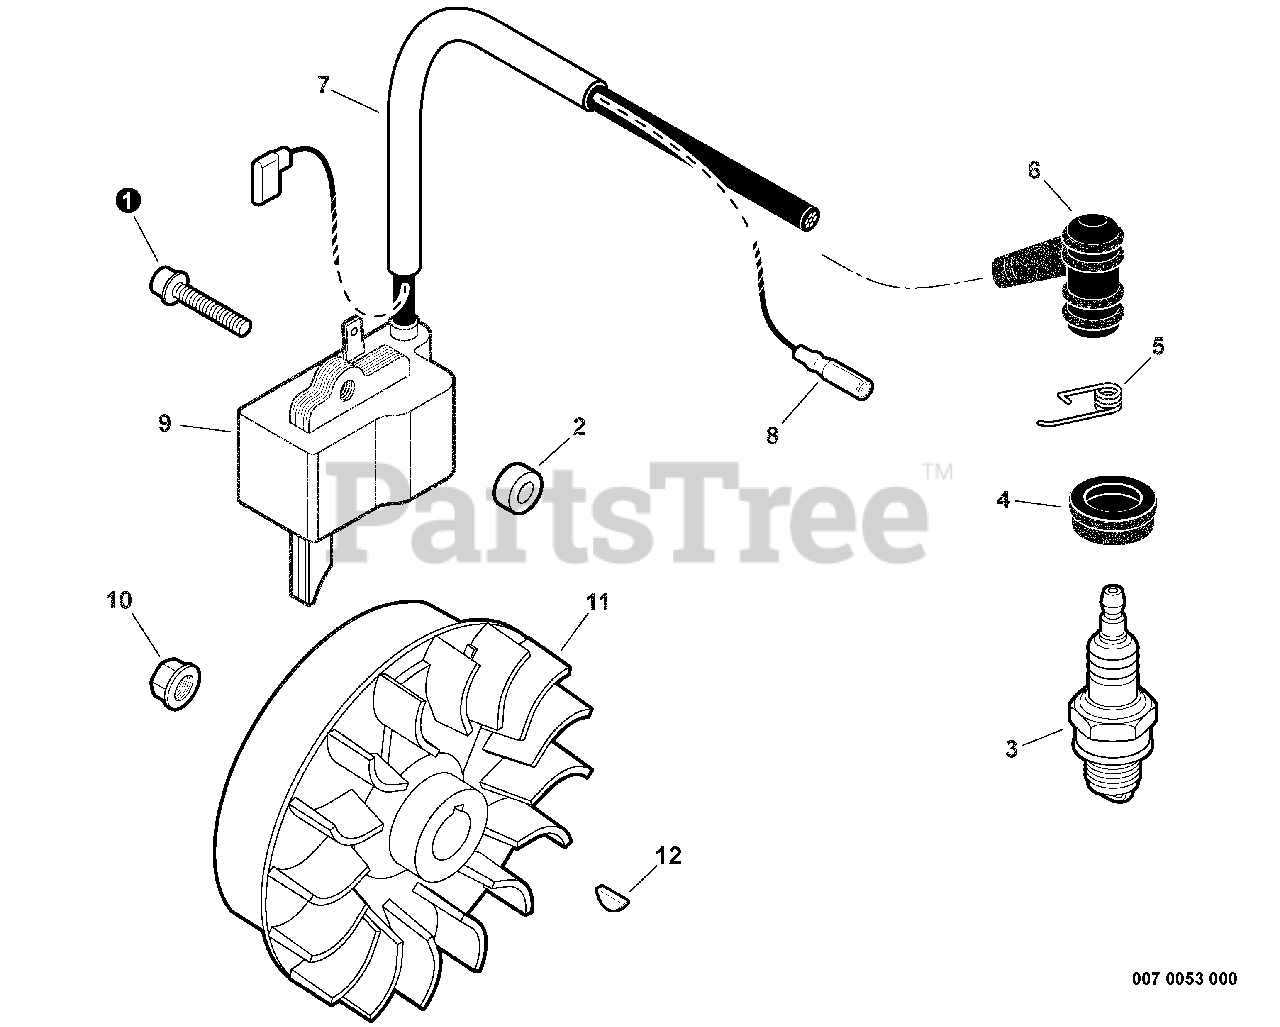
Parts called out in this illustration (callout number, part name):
1	SCREW - 4X10
2	INSULATOR
3	SPARK PLUG -- BPMR-6A
4	COVER, DUST
5	TERMINAL, SPARK PLUG CAP
6	CAP, SPARK PLUG
7	TUBE, INSULATOR
8	LEAD - IGNITION
9	COIL, IGNITION
10	NUT - 8
11	FLYWHEEL
12	KEY - 3X10
